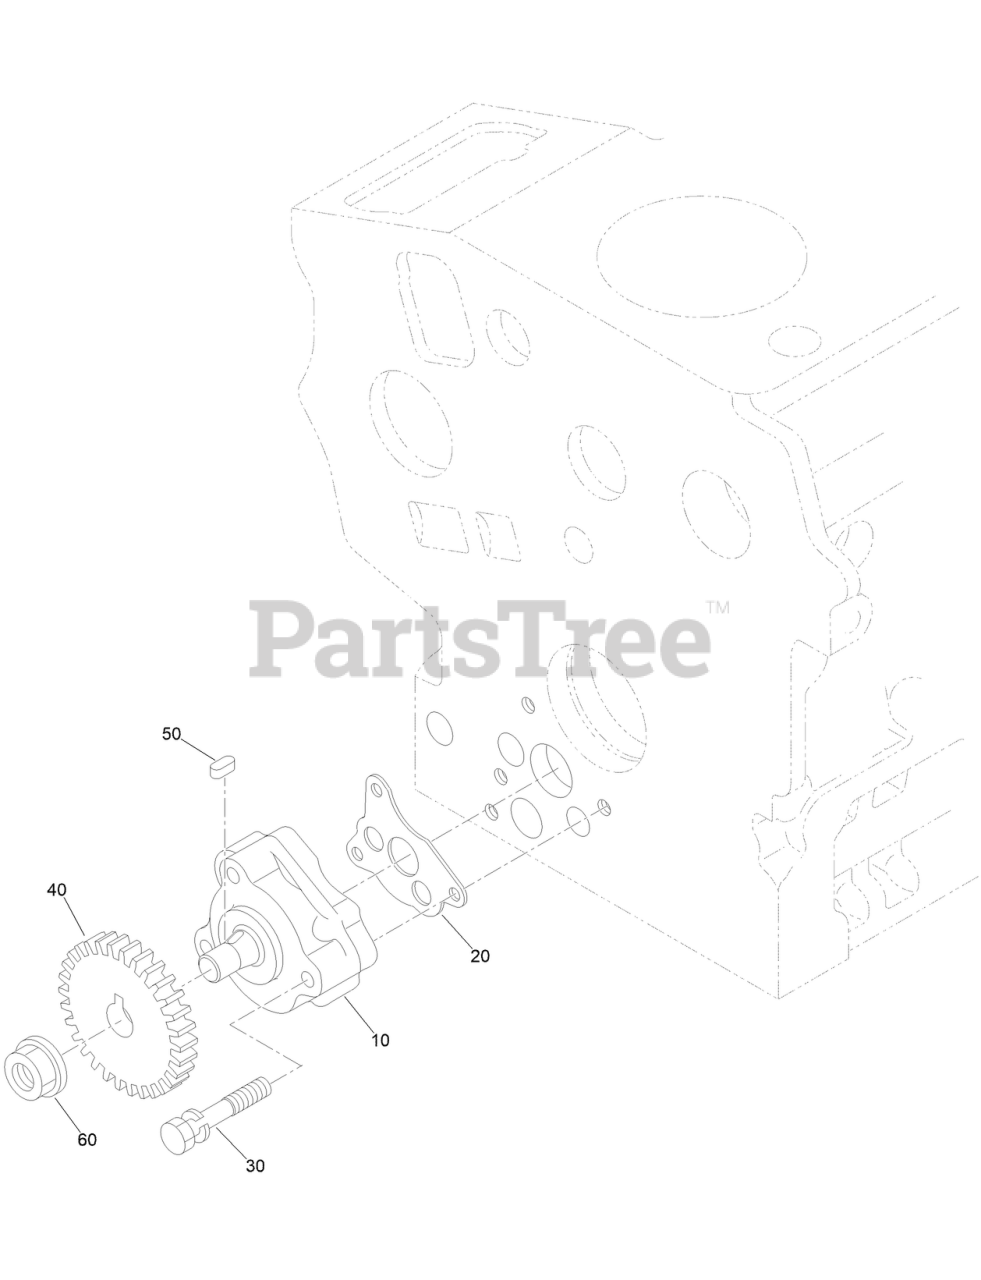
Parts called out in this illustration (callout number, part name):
10	OIL PUMP ASM
20	GASKET-PUMP, OIL
40	GEAR-DRIVE, OIL PUMP
50	KEY-FEATHER
60	NUT-FLANGE
